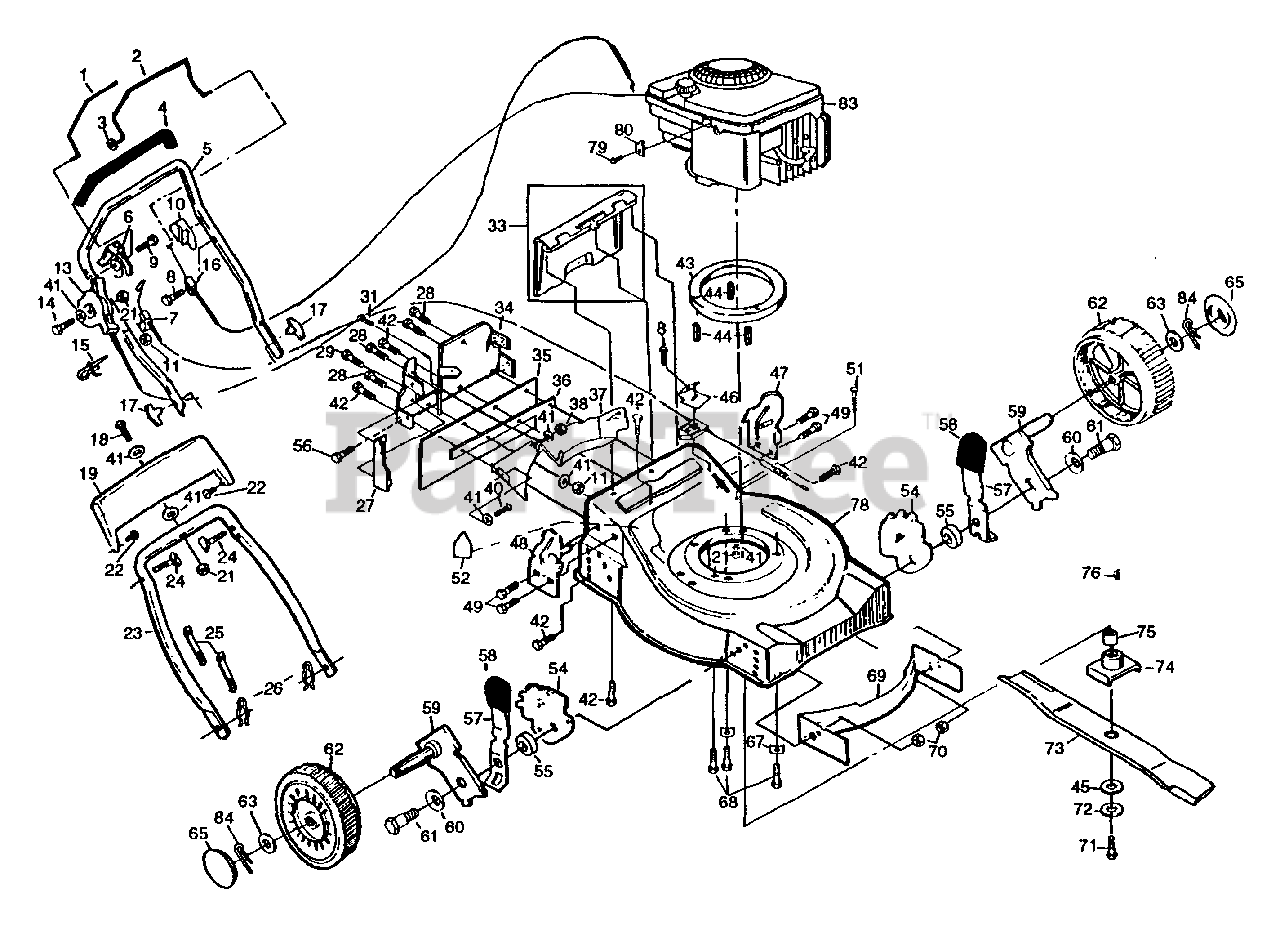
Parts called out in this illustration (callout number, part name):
1	Drive Bar
2	Engine Control Bar
3	Flat Washer
4	Handle Grip
5	Upper Handle
6	Drive Control Actuator
7	Drive Cable Assembly
8	Thread Rolling Screw #10-24 x 3/4
9	Self-taping Screw #10-24 x 5/8
10	Zone Control Actuator
11	Locknut 1/4-20
13	Throttle Control
14	Machine Screw 1/4-20 x 2-1/4
15	Rope Guide
16	Engine Zone Control Cable
17	Handle Knob
18	Hex Washer Head Machine 1/4-20 x 1-1/2
19	Trim Plate Asm.
21	Locknut 1 /4-20
22	Self-tapping Screw #10-24 x 5/8
23	Lower Handle
24	Handle Bolt 5/16-18 x 1-3/4
25	Wire Ties
26	Hairpin Cotter
27	Side Baffle
28	Self Tapping Screw #10-24 x 1/2
29	Hex Head Screw 1/4-20 x 3/4
31	Hex Washer Head Machine Screw #10-24 x 9/16
33	Rear Door Kit
34	Back Plate
35	Rear Skirt
36	Backing Strip
37	Rear Baffle
40	Hex Washer Head Tapping Screw #10-24 x 1/2
42	Hex Tapping Screw 1/4-20 x 1/2
43	Engine Spacer
44	Engine Bushing
46	Bracket Cover
47	Handle Bracket Assembly (Left)
48	Handle Bracket Assembly (Right)
49	Thread Cutting Screw 5/16-18 x 3/4
51	Carriage Bolt 1/4-20 x 1/2
52	Danger Decal
54	Wheel Adjusting Bracket
55	Spacer
57	Selector Spring
58	Selector Knob
59	Axle Arm Assembly
60	Belleville Washer
61	Shoulder Bolt 3/8-16
62	Wheel & Tire Assembly 8.0 x 2.0
63	Washer 17/32 x 1 x 21 Ga.
67	Engine Washer
68	Hex Head Thread Rolling Screw 3/8-16 x 2
69	Front Baffle
70	Lockout 3/8-16
71	Hex Head Machine Screw Gr. 8
72	Helical Washer 3/8
74	Blade Adapter
76	Square Key #HP-505
78	Lawn Mower Housing
79	Thread Rolling Screw #10-32 x 5/8
80	Cable Clamp
83	Engine
84	Retainer Clip
